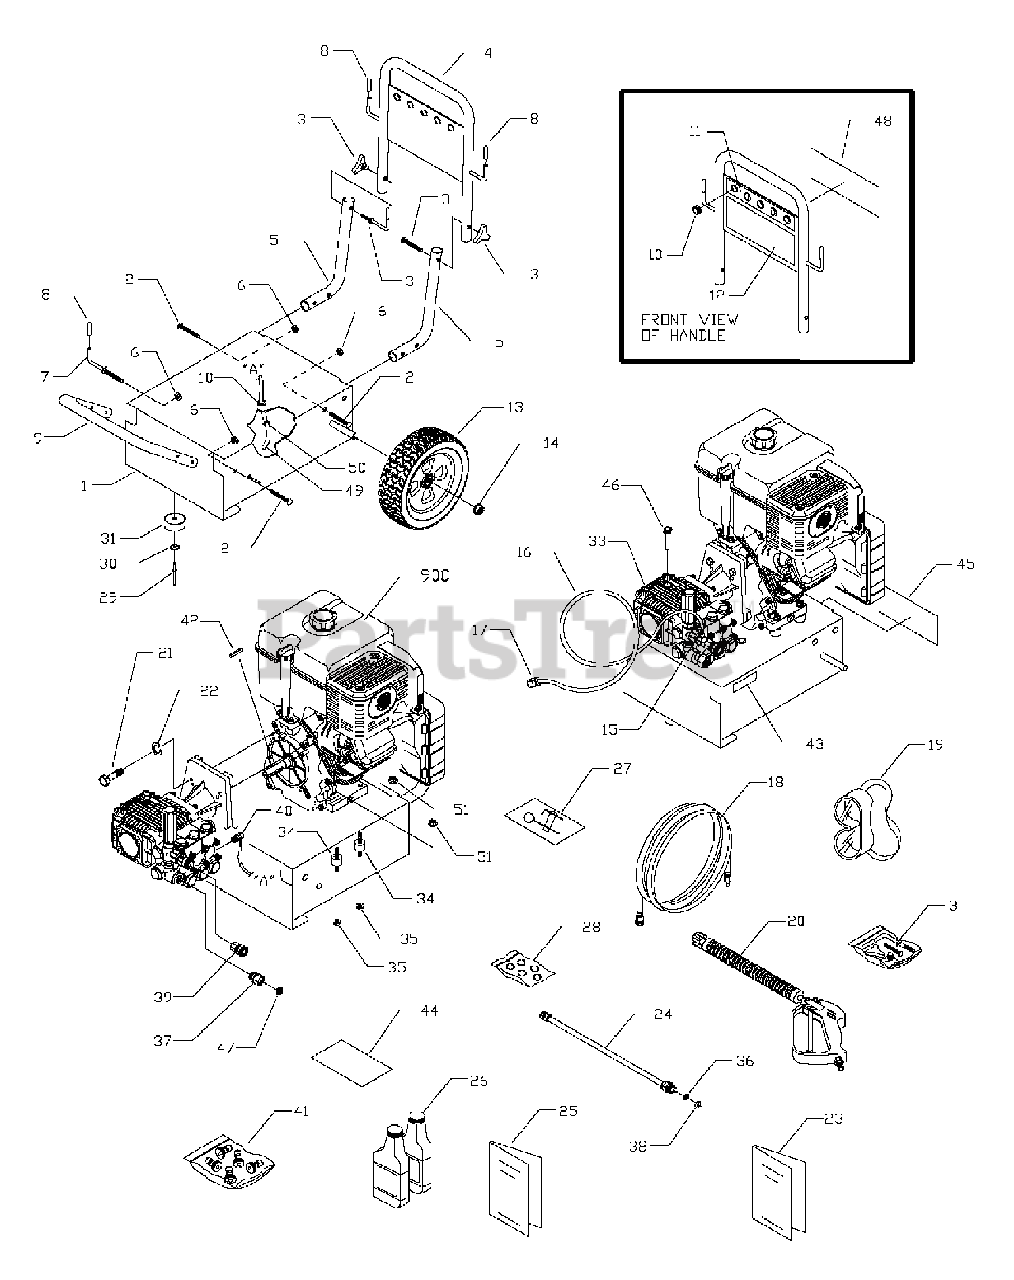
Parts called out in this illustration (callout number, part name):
2	BOLT, Carriage
3	KIT, Handle Hardware
4	HANDLE
5	SUPPORT, Handle
6	NUT, Hex Flange
7	HOOK, 5/16" Square Neck Gun
8	CAP, Black Vinyl
10	GROMMET
11	DECAL, 5 QD Nozzles
12	DECAL, Unit
13	ASSEMBLY, Wheel
15	CLAMP, Hose
16	HOSE, Chemical Inject
17	FILTER, Chemical Hose
18	HOSE
19	GOGGLES, Safety
20	GUN, with Molded Grip
21	CAPSCREW, Socket Head
22	LOCKWASHER
23	MANUAL, Owners
24	ASSY., Wand Ext. with QD
25	MANUAL, B&S, Vanguard
26	OIL BOTTLE
27	KIT, Nozzle Cleaning
28	KIT, O-Ring Maintenance
29	BLIND RIVET
30	FLAT WASHER
31	VIB MOUNT, Donut Type
33	PUMP, Assembly (see pages 18-21)
34	MOUNT, Vibration
35	NUT, M8, Flange
36	SCREEN, Gun Inlet
37	INLET, Garden Hose
38	O-RING, High Pressure Hose
39	QUICK CONNECT
40	VALVE, Thermal Relief
41	KIT, Nozzles QD
42	KEY
43	DECAL, Cool Down System
44	CARD, Owners Registration
45	DECAL, PW, Snapper
46	DIPSTICK, Pump
47	FILTER, Inlet
48	DECAL, Warning/Start
49	HOSE, Thermal Relief
50	CLAMP, Hose Band
51	NUT, M8, w/Washer
900	§ ENGINE
